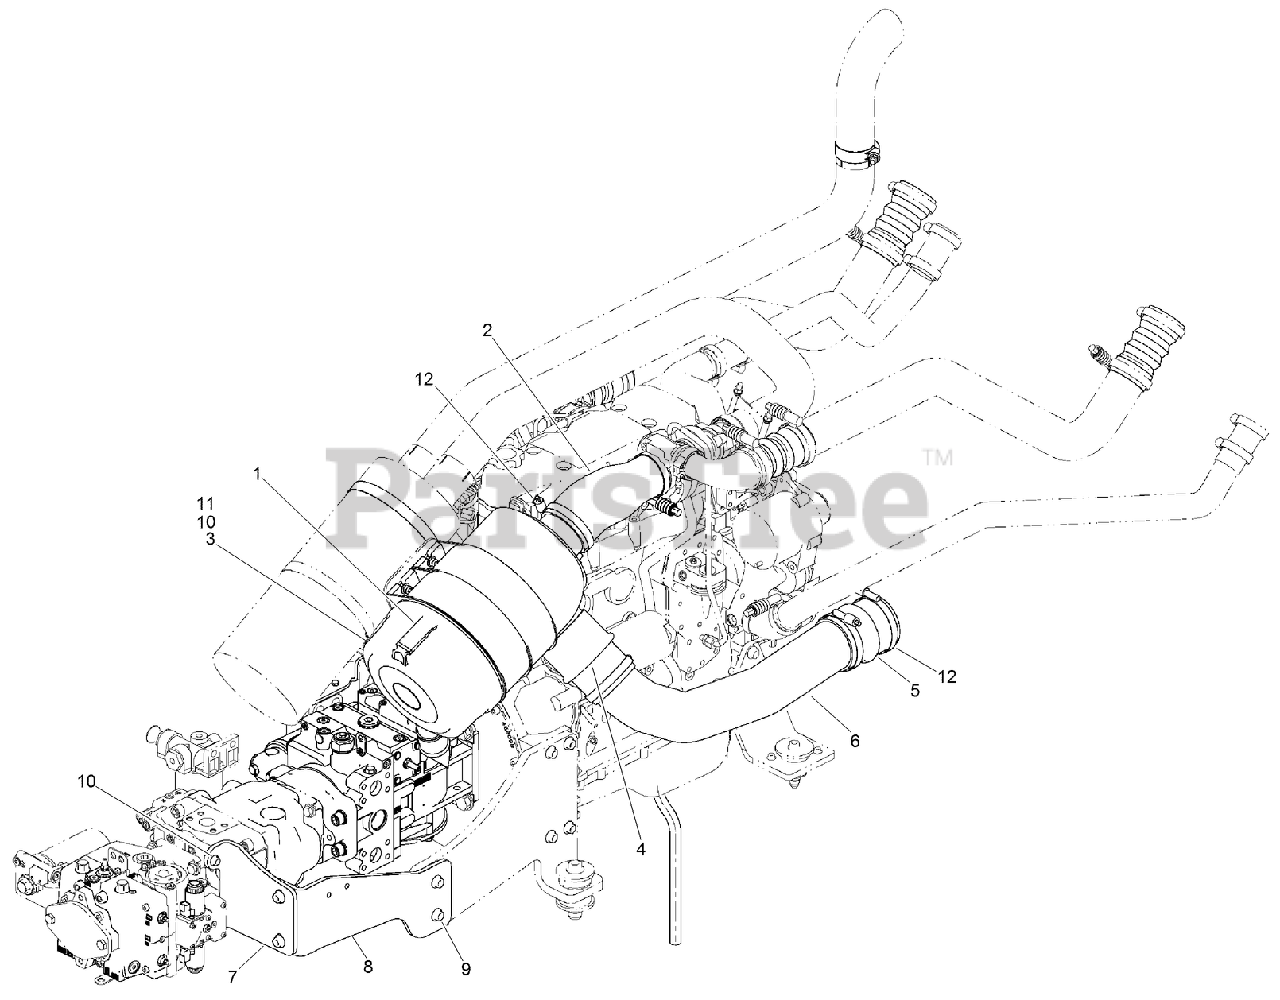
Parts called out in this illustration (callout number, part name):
1	SCREW-FLANGE
2	AIR-INTAKE - Out
3	ASSEMBLY - Air Cleaner
4	REDUCER, HUMP HOSE - 4-1/2 to 4
5	ADAPTER, HUMP HOSE - 4
6	AIR INTAKE - Fresh Air
7	BRACKET - Mounting, Pump
8	BRACKET - Mounting, Center
9	SCREW-HHF
10	SCREW-HH
11	NUT-FLANGE, NYLOCK
12	CLAMP-TORQUE, CONSTANT
